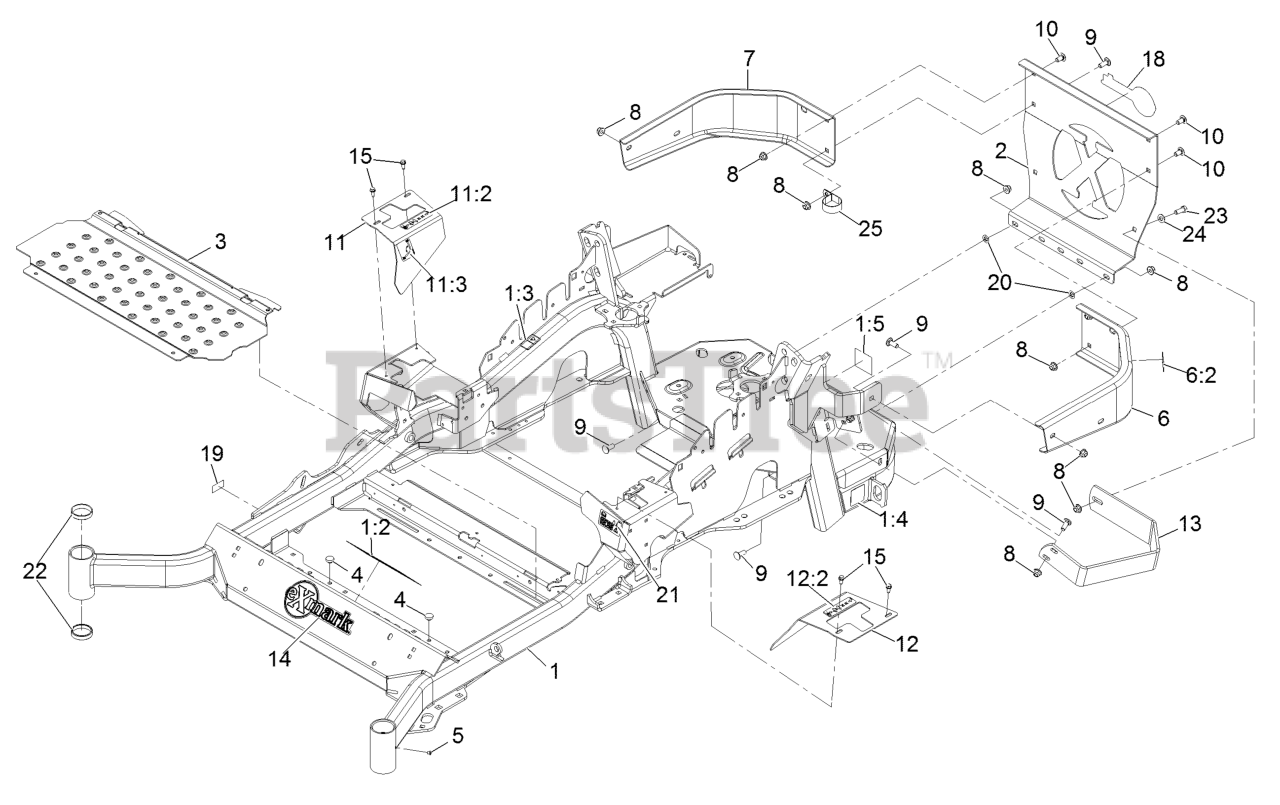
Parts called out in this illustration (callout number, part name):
1:2	DECAL-DANGER
1:3	DECAL-WARNING
1:4	DECAL-HAZARD, PINCHED FINGER
1:5	DECAL-SPARK ARRESTER
2	PLATE,REAR GUARD
6	LH BUMPER ASM
6:2	DECAL-WARNING
7	BUMPER-RH
8	NUT-HF, NI
9	SCREW-CARR
10	SCREW-CARR
11	RH MOTION CONTROL COVER ASM
11:2	DECAL-CONTROL, MOTION
11:3	DECAL-PARK BRAKE, CE
12	LH MOTION CONTROL COVER ASM
12:2	DECAL-CONTROL, MOTION
13	GUARD-MUFFLER
14	DECAL-EXMARK LOGO
15	SCREW-HWH
18	DECAL-EXMARK LOGO
19	Decal-Patent Ttco.Com
20	NUT-PUSH
21	DECAL-FUEL FILL, CE
22	CUP-BEARING
23	SCREW-HH
24	WASHER-FLAT
25	CLAMP-R
